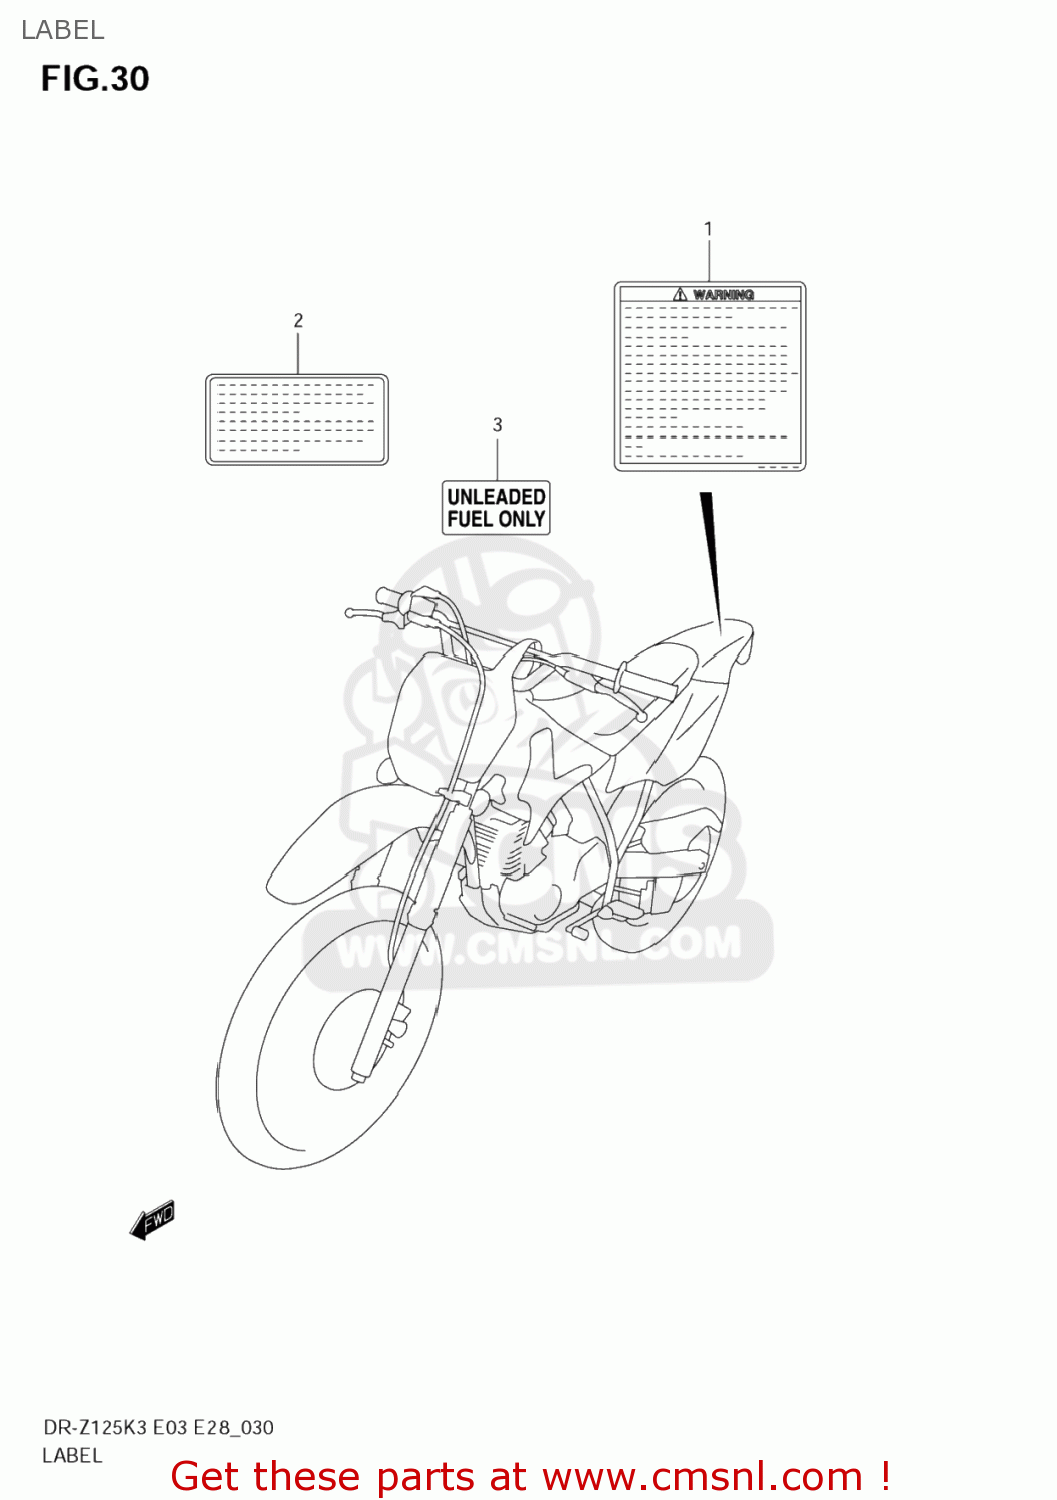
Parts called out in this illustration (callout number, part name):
1	LABEL,GENERAL WARNING
2	LABEL,MANUAL NOTICE
3	LABEL,FUEL
4	MANUAL,OWNER'S
